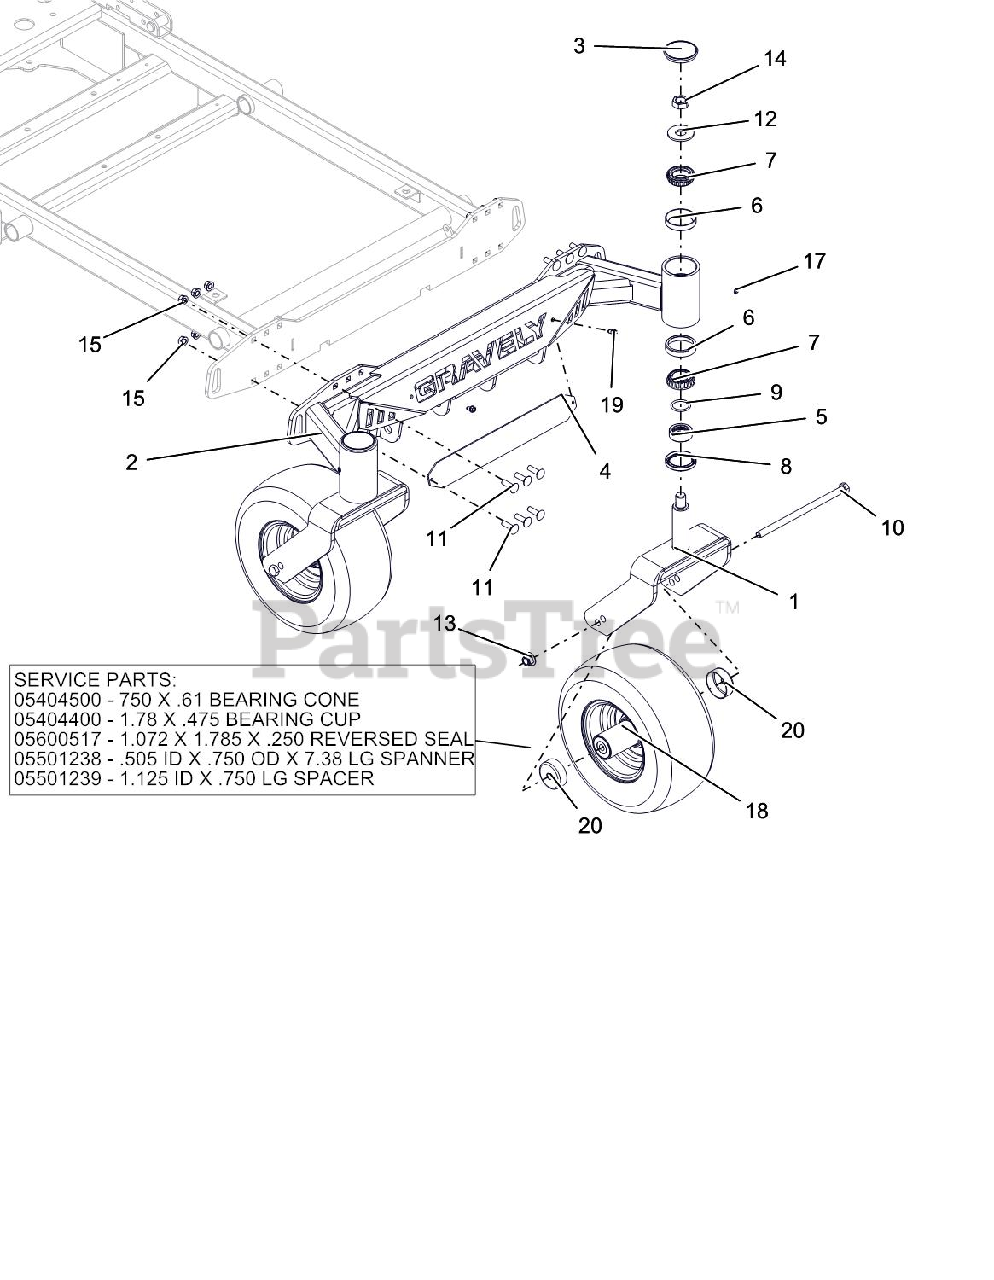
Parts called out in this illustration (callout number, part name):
1	CASTER FORK WMT - RED
2	WMT, 48 FRONT AXLE
3	CAP, DUST
4	BACKER, NAMEPLATE
5	SPACER, FRONT CASTER FORK
6	BRG-CUP 2.328X.465
7	BRG-CONE 1.25X.66
8	SEAL, OIL 1.75 X 2.332 X .312
10	@BLT-HEX .50-13X9.00 GR5 YWZC
11	@BLT-RDHDSQNK .38-16X1.25 G5YZ
12	@WSHR-FL-STL.812X2.00X.148YWZC
13	@NUT-LK-NYL-FLG .50-13 YWZC
14	NUT-JAM TOPLK .75-16 YWZC
15	@NUT-LK-TOP-FLG .38-16 YWZC
17	FTG, .25-28 FLUSH MNT GREASE
18	BRG-CONE .750X.61
18	BRG-CUP 1.781X.475
18	SPACER, 1.125 ID X .750 LG
18	SPANNER,.505ID X.750OD X7.38LG
18	SEAL, 1.125 X 1.781 X .469
18	ASM, WHL/TIRE 13X6.50-6 SEMI
19	SCR-TAP .25-20X.50 HWH TR YWZ
20	SHIELD, WHEEL BEARING
